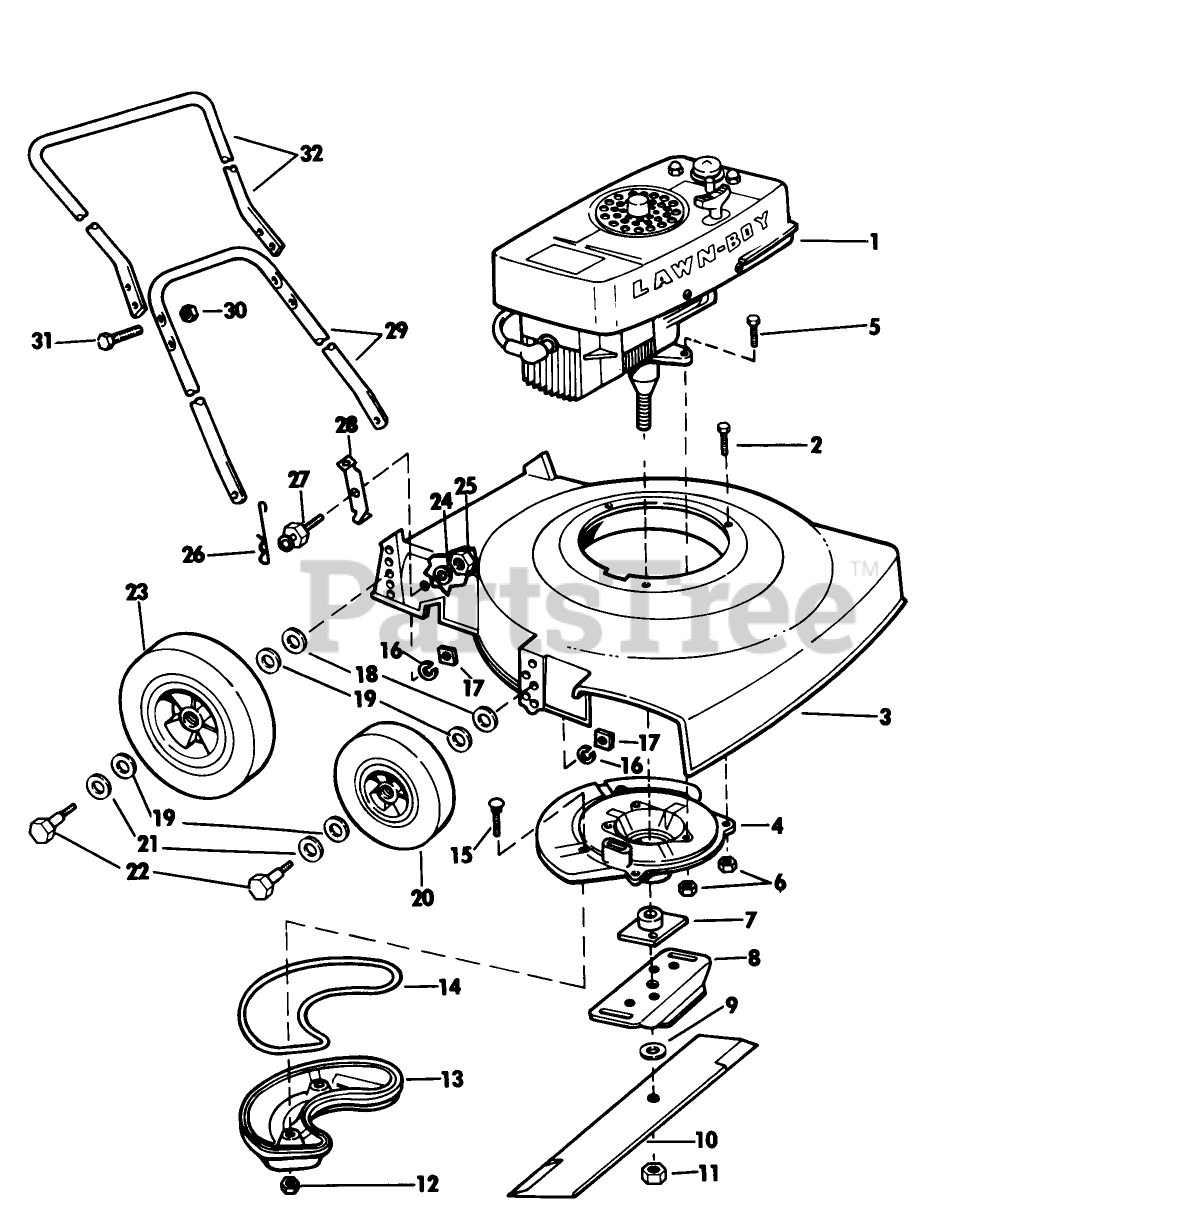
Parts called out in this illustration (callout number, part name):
7	PLATE AND COLLAR ASM
11	NUT-BLADE
12	LOCKNUT E
16	WASHER, LOCK
18	WASHER WROUGHT
20	WHEEL & TIRE KIT
24	Lockwasher
